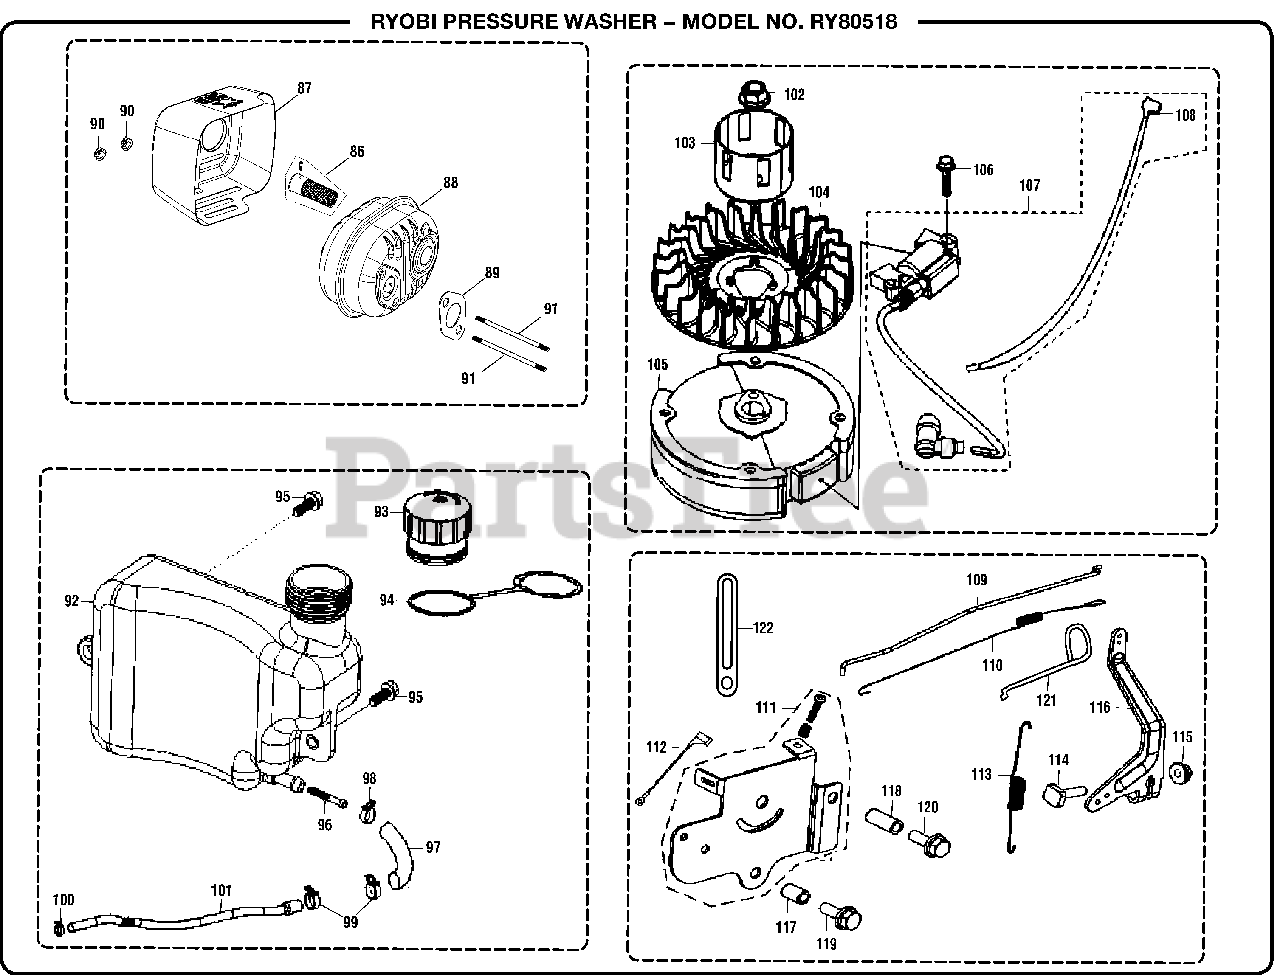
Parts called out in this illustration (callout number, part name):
86	Catalytic converter
87	Muffler Outer Cover
88	Muffer Assembly
89	Exhaust Outlet Gasket
92	Fuel Tank Assembly
105	Flywheel Assembly
107	Ignition Coil Stop Wire
110	Throttle Valve Return Spring
111	Throttle Control Bottom Plate
112	Stop Engine Switch Ground Wire
113	Governor Spring
114	Governor Support Bolt
116	Governor Support Assembly
119	Bolt (Hex Flange Hd.)
